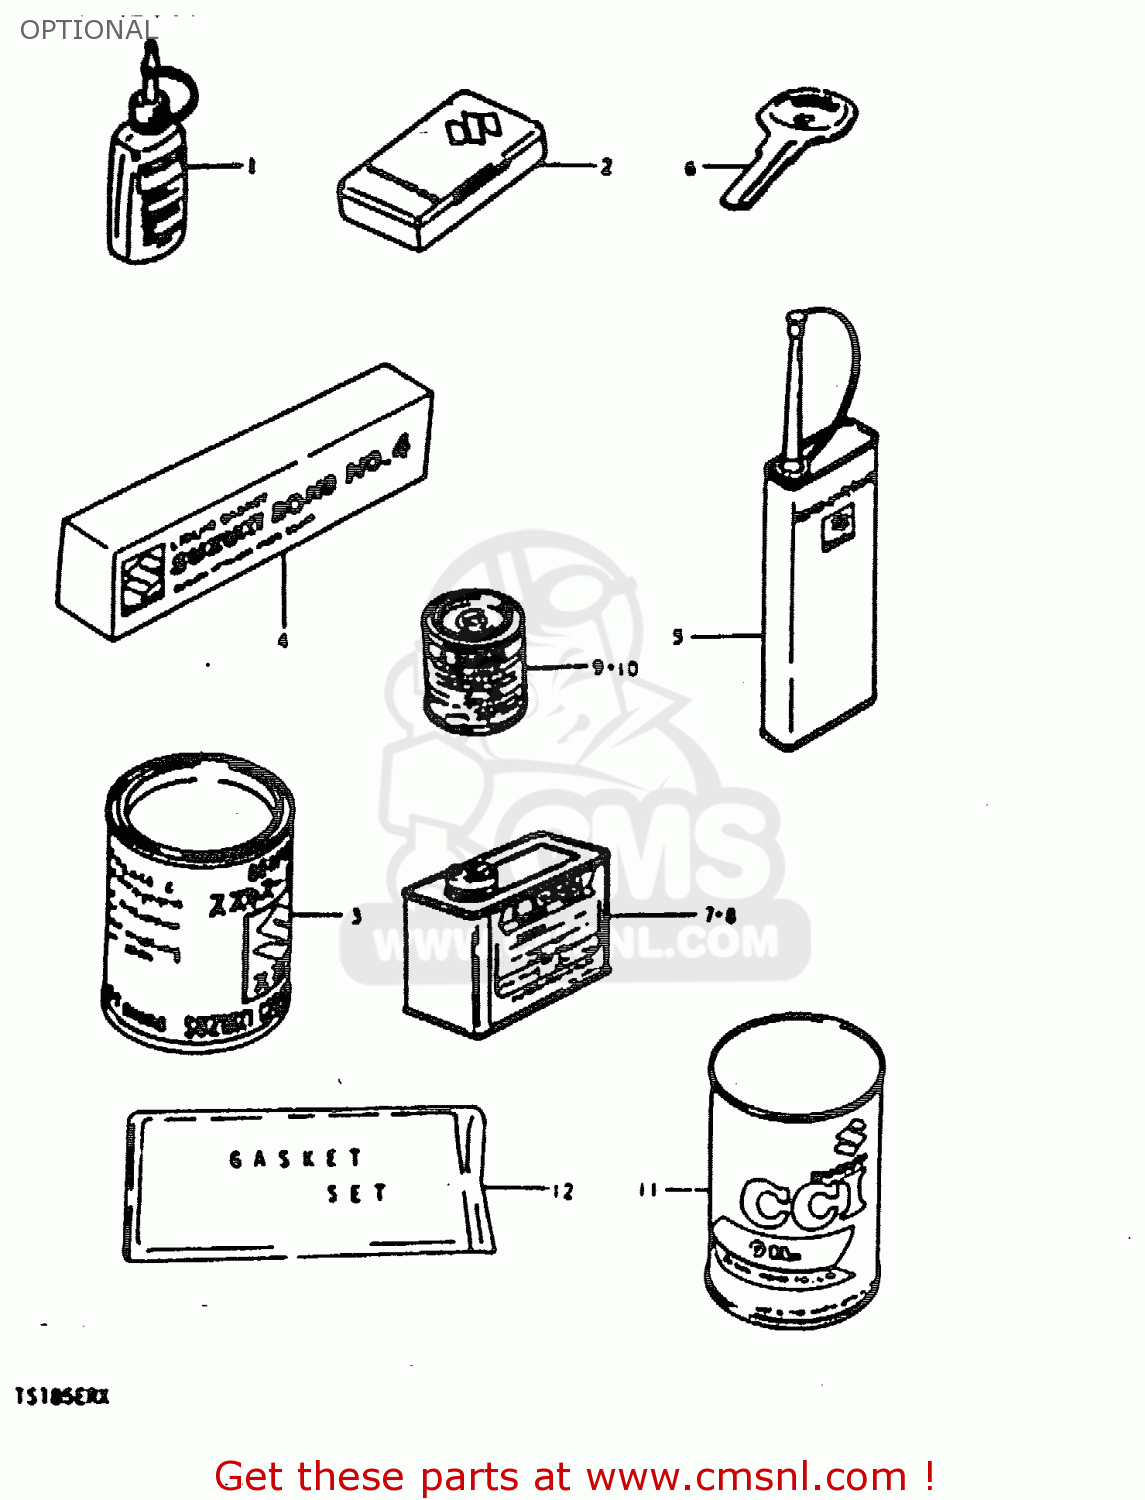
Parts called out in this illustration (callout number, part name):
1	THREAD LOCK NO.1303B PURPL 50G
2	TUBE REPARING TOOL
3	GREASE(C)EP2 LITHIUM 150G
4	BOND 1104
5	THREAD LOCK NO.1401 CLEAR 200G
6	KEY,BLANK
7	PAINT (BLACK)
8	PAINT (EGRET WHITE)
9	PAINT,BLACK
10	PAINT,BLACK
11	CCI OIL
12	GASKET SET (MCA)
